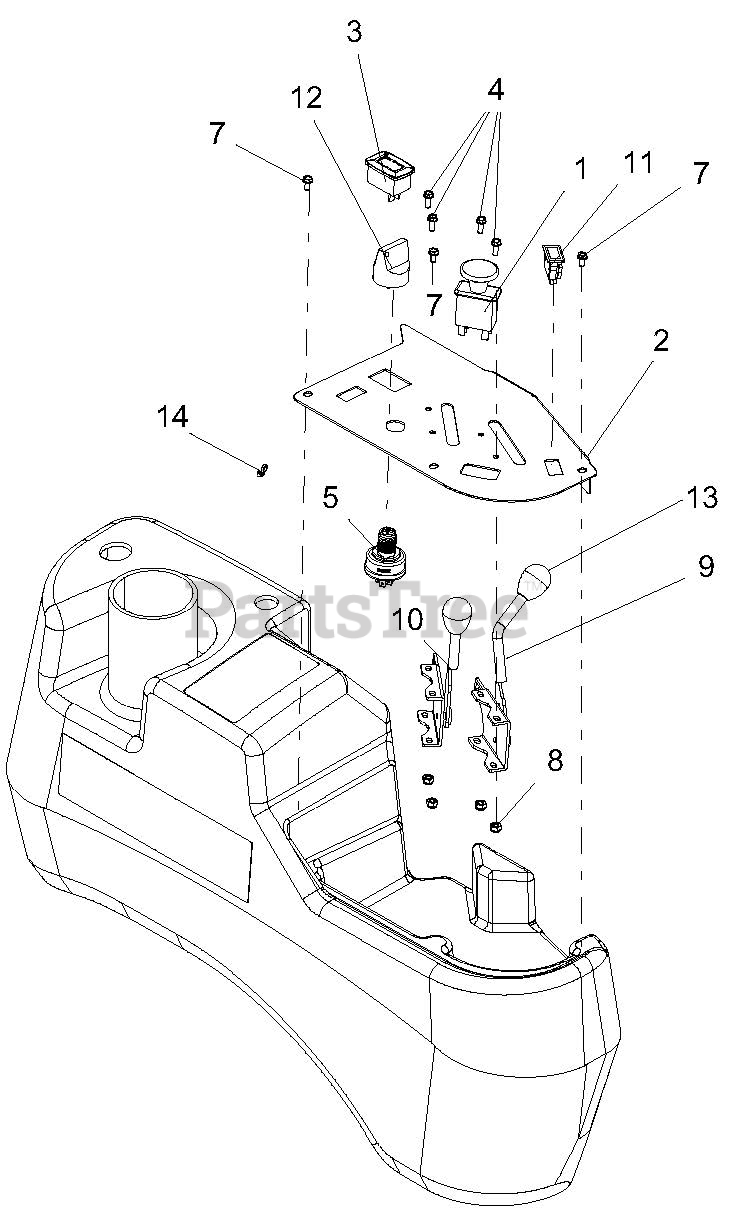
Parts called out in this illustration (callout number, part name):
1	SWITCH, CLUTCH
2	PANEL, CONTROL
3	METER, HOUR W/MAINTENANCE
4	SCR-MCH 10-24X.50 HWH YWZC
5	SWITCH, IGNITION
7	SCR, HWH 10-24x.38 STAINLESS
8	NUT-LK-NYL #10-24 YWZC
9	CABLE, PRO-CONTROL THROTTLE
9	CABLE-THROTTLE 53"
10	CABLE, PRO-CONTROL CHOKE
11	LIGHT, INDICATOR
12	KEY, W/ COVER
13	KNOB, CONTROL BLACK .38-16X.50
14	CABLE TIE W/ TREE
